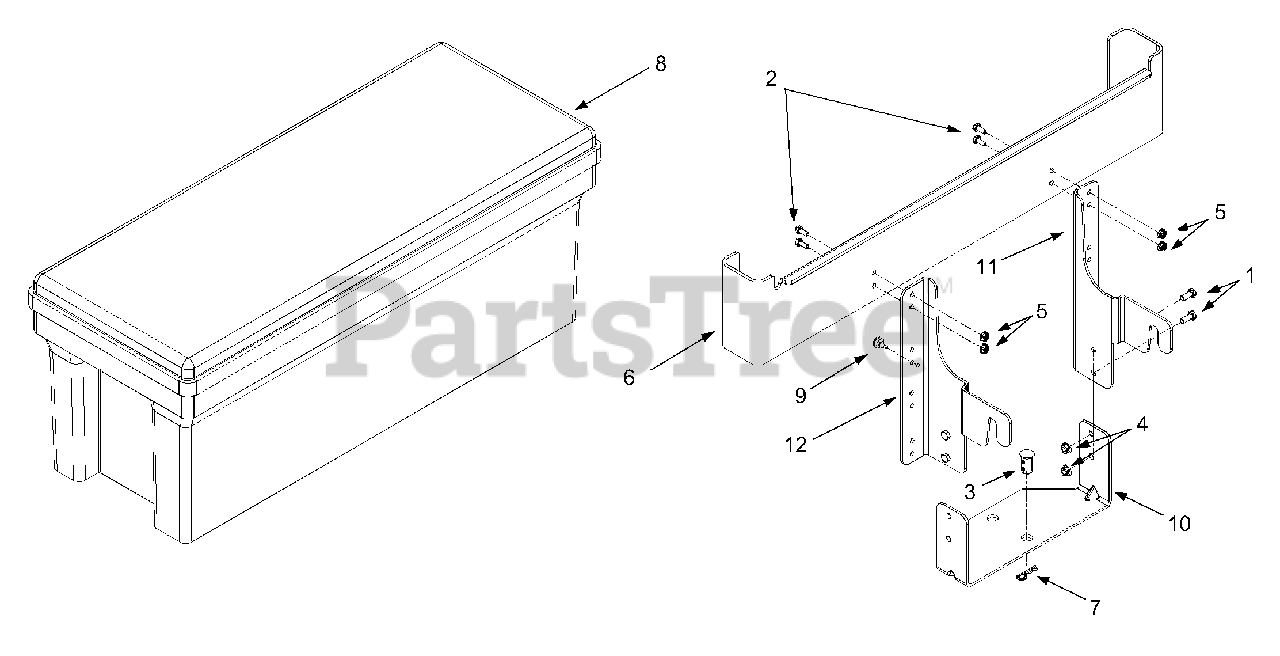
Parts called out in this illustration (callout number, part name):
1	Hex Cap Screw, 5/16-18 x .75
2	Hex Cap Screw, 1/4-20 x .62
3	Clevis Pin
4	Hex Flange Lock Nut, 5/16-18
5	Hex Flange Lock Nut, 1/4-20
8	Plastic Tool Box
9	Bumper, .62 Dia. x .3
10	Cross Support Bracket
11	LH Support Bracket
12	RH Support Bracket
